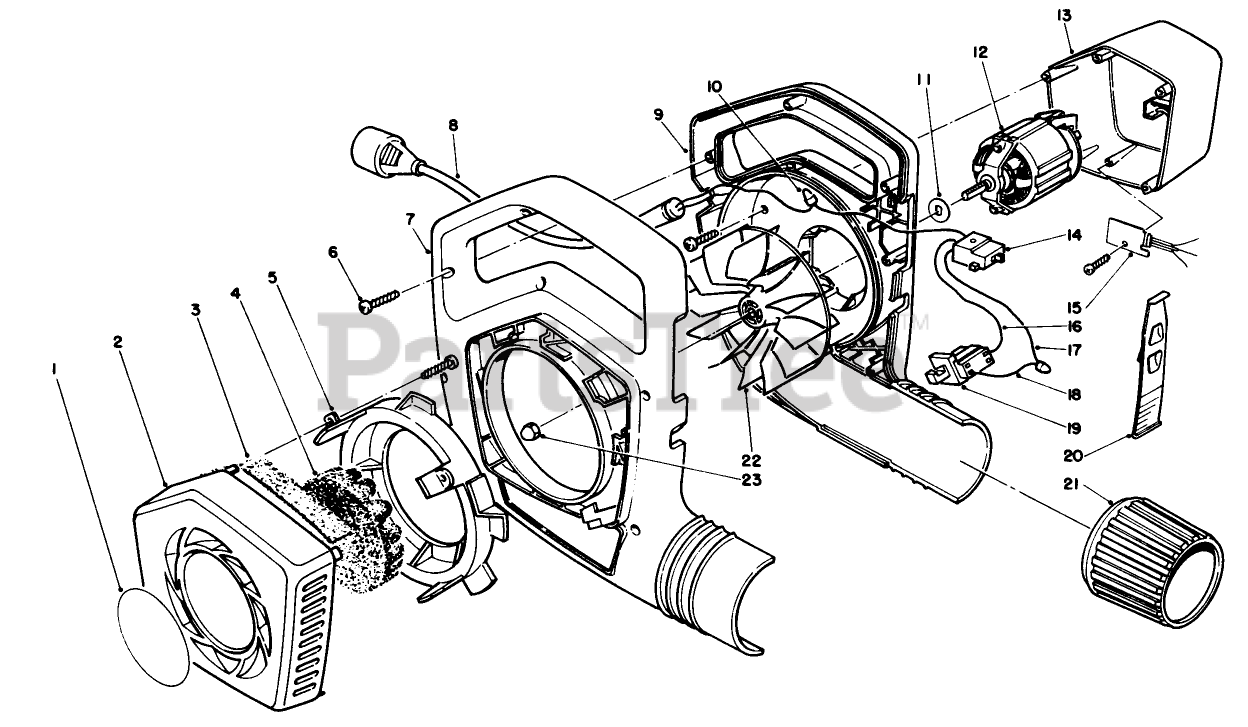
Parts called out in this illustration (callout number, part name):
1	DECAL, COVER
2	Cover-Intake
3	TOP FOAM
4	CENTER FOAM
5	Ring-Coupling
6	Screw
7	Housing-Blower, R.H.
8	POWER SUPPLY CORD,9.5"
9	Housing-L.H.
10	Connector
11	Washer-Impeller
12	Motor-Blower
13	Cover-Motor
14	Switch-Varispeed
15	SPEED CONTROL ASSEMBLY
16	WIRE -INTERNAL
17	WIRE INTERNAL, WHITE
18	WIRE, 3 INCH
19	SWITCH-INTERLOCK
20	HOT STAMPED CAM SWITCH
21	Collar-Output
22	IMPELLER, 850 BLOWER
23	NUT-LOCK, CAP
